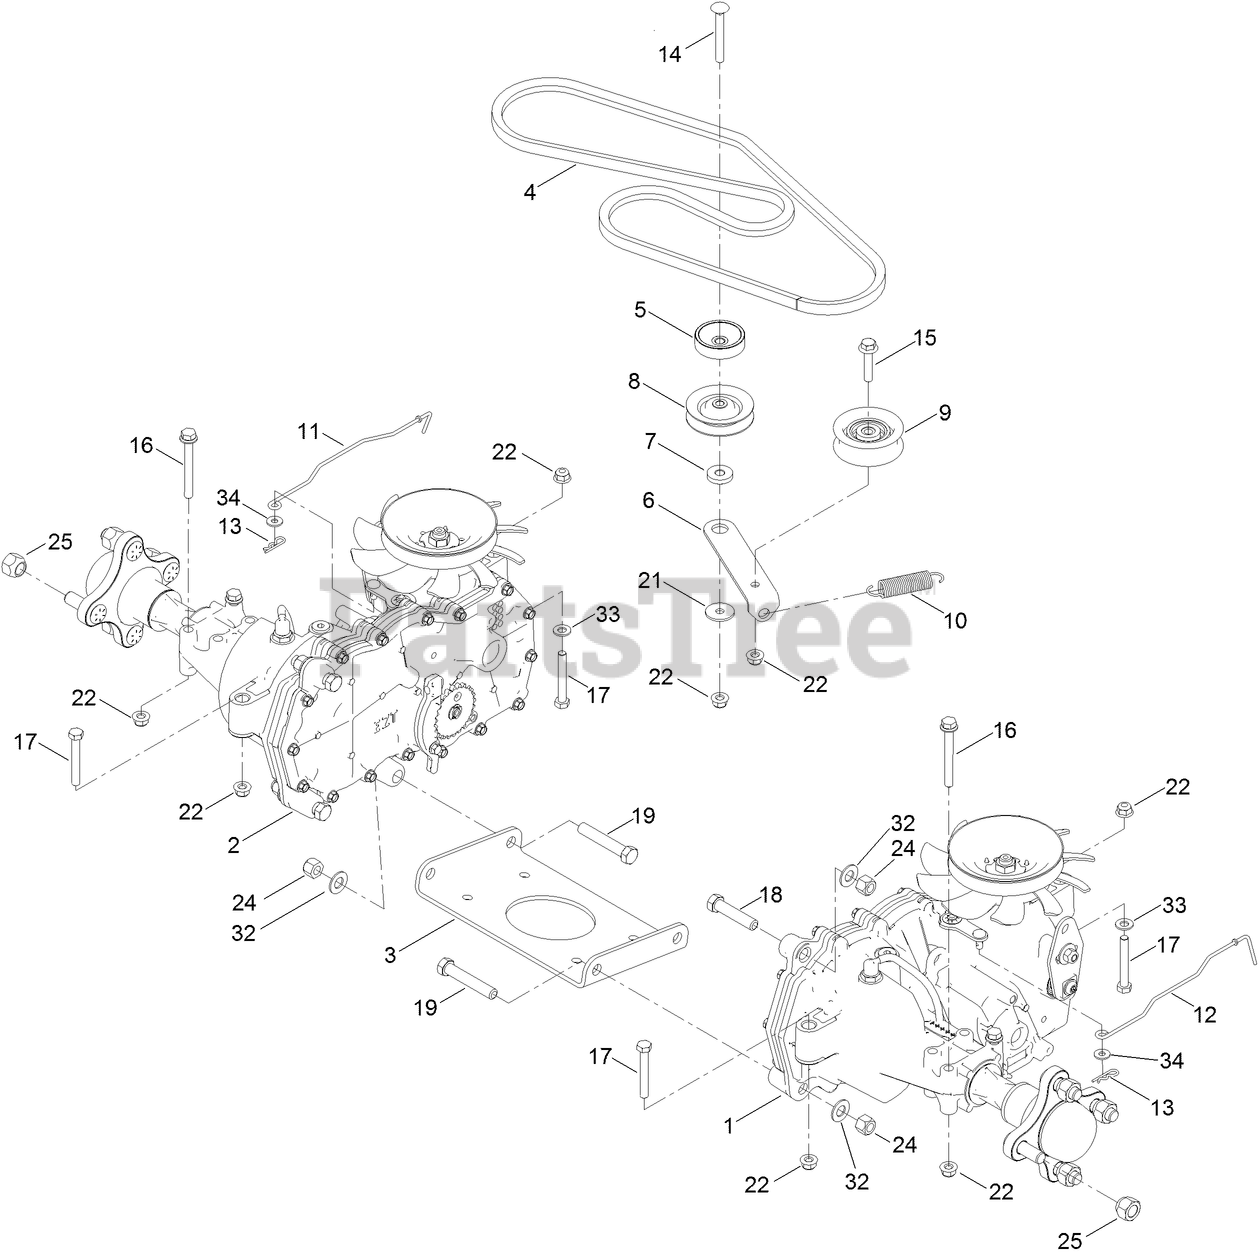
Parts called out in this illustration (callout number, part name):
1	LH HYDRO TRANSAXLE ASM
2	RH HYDRO TRANSAXLE ASM
3	CROSSPLATE-HYDRO
6	Arm-Idler
7	SPACER-ARM, IDLER
9	Pulley-Idler, Flat
10	Spring-Return, Pedal
11	Rod- Bypass,RH
12	Rod- Bypass,LH
14	SCREW-CARR
15	SCREW-HHF
16	SCREW-HHF
17	SCREW-HH
18	SCREW-HH
19	SCREW-HH
21	WASHER-PIVOT
22	NUT-HF, NI
24	NUT-LOCK, NI
25	NUT-LUG
32	WASHER-FLAT
33	WASHER-PLAIN
